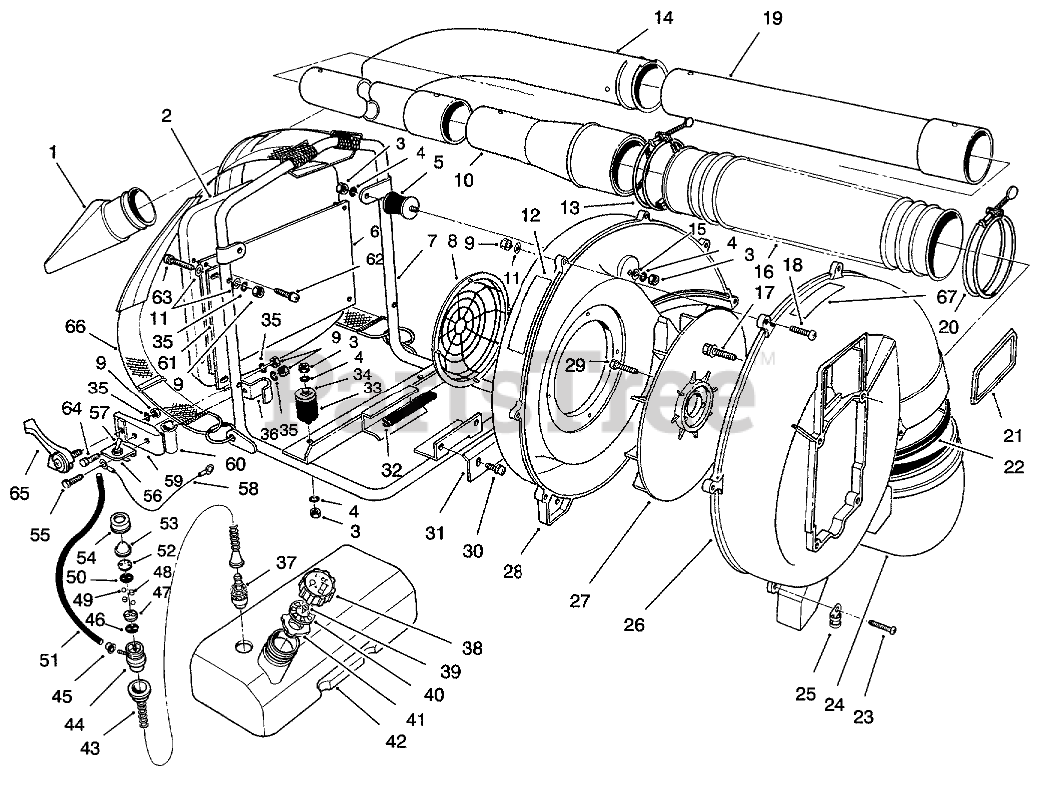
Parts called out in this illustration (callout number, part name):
1	NOZZLE
4	Washer-Lock
5	CUSHION RUBBER
6	PLATE
7	FRAME
8	FAN COVER
11	WASHER
12	DECAL - WARNING
13	WIRE BAND
15	WASHER
17	BOLT & WASHER
18	SCREW & WASHER
20	WIRE BAND
21	TORO LOGO PLT
22	DUST SEAL RING
23	SCREW
24	ELBOW
25	Clamp
26	FAN CASE
28	FAN CASE
29	BOLT ? WASHER
30	BOLT & WASHER
31	STOPPER
32	CUSHION RUBBER
33	CUSHION RUBBER
34	CUSHION HOLDER
35	SPRING WASHER
36	STOPPER
37	FUEL FILTER
38	Gas Cap Assembly (Incl. Ref. #39-41)
39	Valve-Breather
40	Holder
41	Gasket
42	Fuel Tank Assembly (Incl. Ref.#37-41, 43, 44, 46-50, & 52-54)
43	HOSE, SUCTION
44	Primer-Pump (Incl. Ref. #47-54)
46	GASKET
47	SEAT VALVE
48	SPONGE
50	GASKET
51	FUEL TUBE
52	SEAT VALVE
54	PUMP CAP
56	SWITCH BRACKET
57	STOP SWITCH
58	WIRE LEAD
59	BRACKET
60	BUSHING
61	PLATE
62	SCREW & WASHWER
63	SCREW & WASHER
65	THROTTLE LEVER
66	SHOULDER HARNESS
67	DECAL - SOUND LEVEL
